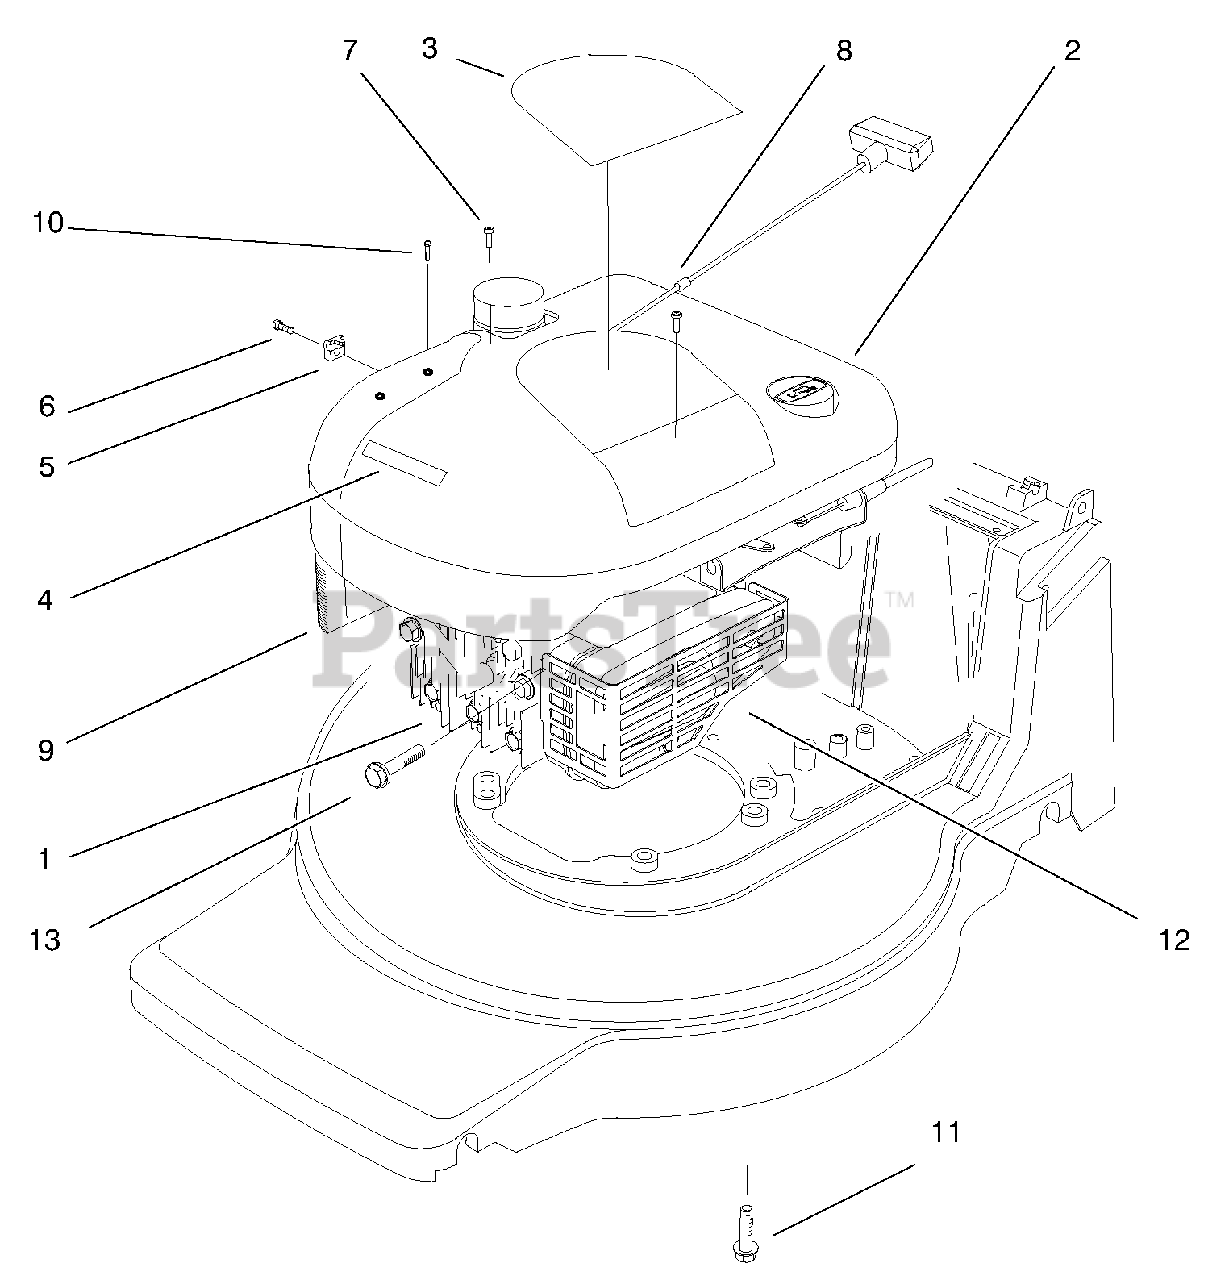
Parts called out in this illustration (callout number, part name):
1	Engine
2	Shroud-Engine
3	Decal-Recoil
4	Applique-Shroud
5	Clamp-Casing
6	Screw-Clamp
7	Screw-Mtg
8	Rope-Stop
10	Screw-Air Cleaner
12	Shield-Muffler
13	Screw-HWHTF
